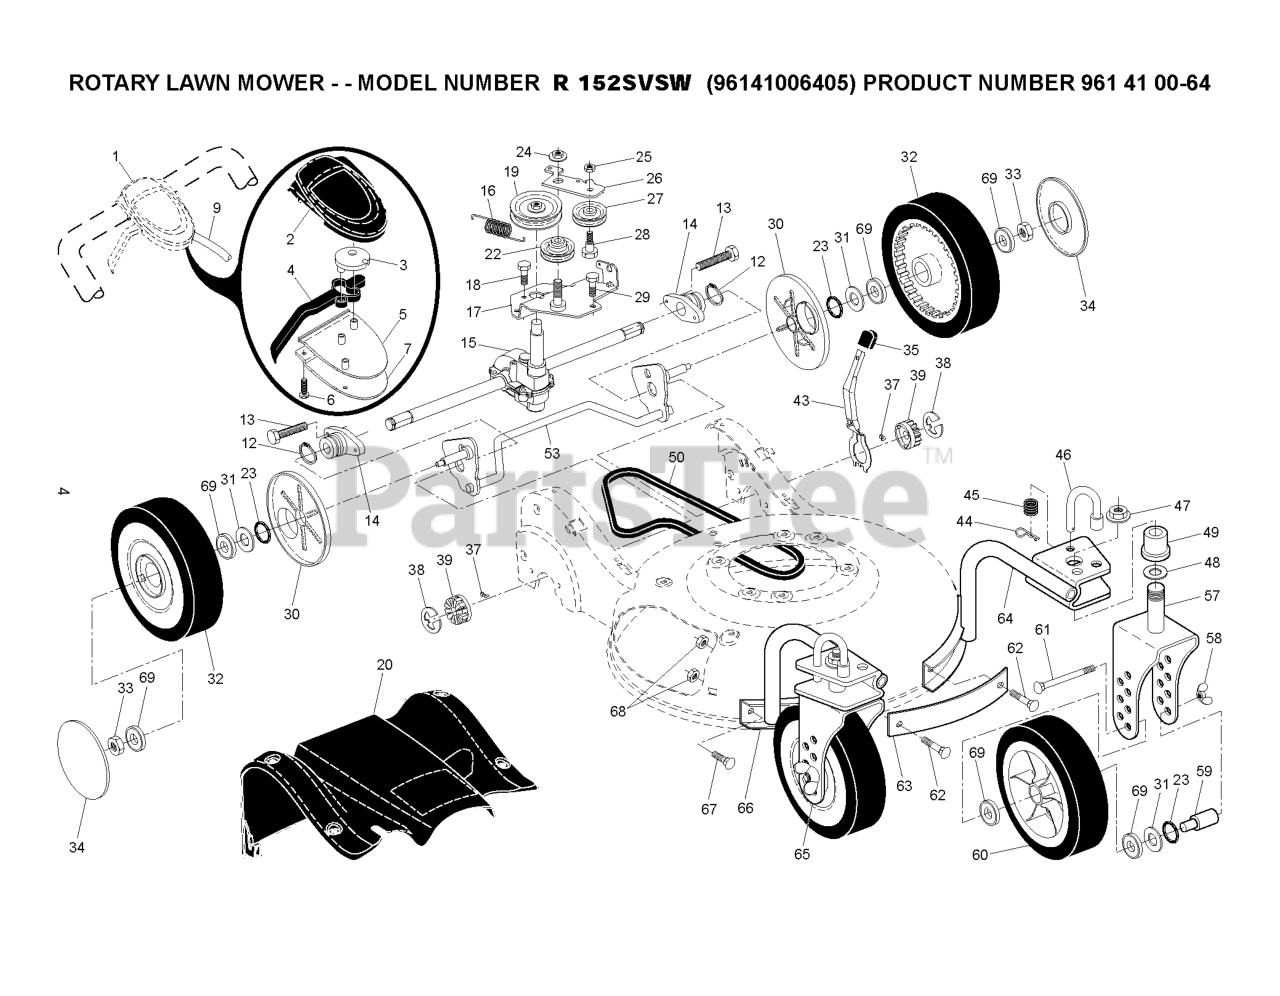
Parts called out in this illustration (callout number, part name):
1	Drive Control Assembly, Complete
2	COVER TOP AUTO WALK CONTROL
3	PULLEY.CAM.DRIVE.CONTROL.HV
4	LEVER.BLACK
5	COVER BOTTOM AUTO WLK CONTROL
6	SCREW, PHILLIPS HEAD 10 X 5/8
7	BRACKET.DRIVE.CONTROL.MOUNT.BL
9	ASM.CABLE.
12	RETAINING RING (2 2)(3 2)
13	HINGE SCREW
14	BEARING / AXLE SUPPORT
15	TRANSMISSION.21.HV.RWGD.AW/EZ
17	BRACKET, GEAR CASE / DRIVE
19	RP PULLEY.DRIVE.EZ
20	COVER.DRIVE.REAR.21.HV.GRAY
22	PULLEY.IDLER.V-BELT
23	O-RING
24	NUT.HEX.FLANGE.3/8-16.LOCKNUT
25	NUT.CENTERLOCK.5/16-
26	ARM.IDLER.BZP
27	IDLER PULLEY
28	SHOULDER BOLT
29	SCREW 14-20 X 5/8
30	DUST COVER, WHEEL
31	WASHER.FLAT.1/2
32	WHEEL.9X2.25.LP.TIGER.BLACK
33	NUT.HEX.FLANGE.3/8-16.LO(3 2)
34	HUBCAP.WHEEL.5.SPOKE.SILVER
35	KNOB.SELECTOR.SPRING.BLACK(3 2
37	PAWL, DRIVE
38	E-RING 7/16 RE
39	PINION.14.TEETH.FGD
43	LEVER, SELECTOR, HEIGHT, REAR
44	SPRING RETAINER
47	NUT.HEX.FLANGE.3/8-16.LOCKNUT
48	WASHER.FLAT.1/2
50	BELT, DRIVE
53	SHAFT.ASM.REAR.TORQUE.HV.BZP
57	BRACKET.WHEEL.ASM.LT.CASTER.OR
58	NUT.WING.5/16-18.YELLOW
60	WHEEL.9X2.25.LP.TIGER.SILVER
61	CARRIAGE BOLT
63	STRAP.FRONT.CASTER.ORANGE
64	SUPPORT.TUBE.ASM.LT
65	BRACKET.WHEEL.ASM.RIGHT.ORANGE
66	SUPPORT.TUBE.ASM.RT
68	NUT
69	BEARING.8".WHEEL
